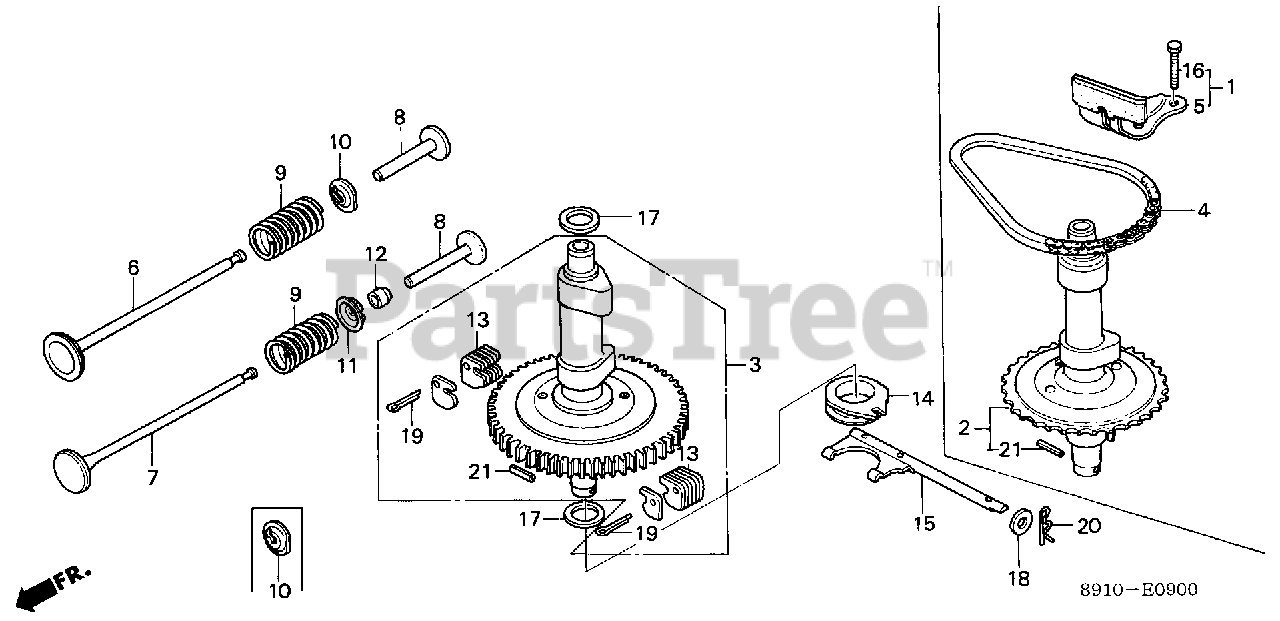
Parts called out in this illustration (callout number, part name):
3	CAMSHAFT ASSY.
6	VALVE, IN.
7	VALVE, EX.
8	LIFTER, VALVE (45.89MM)
8	LIFTER, VALVE (46.04MM)
8	LIFTER, VALVE (46.19MM)
8	LIFTER, VALVE (46.34MM)
9	SPRING, VALVE
10	RETAINER, VALVE SPRING
11	RETAINER, VALVE SPRING
12	ROTATOR, EX. VALVE
13	WEIGHT, GOVERNOR
14	SLIDER, GOVERNOR
15	SHAFT, GOVERNOR
17	WASHER, THRUST (18MM)
18	WASHER, PLAIN (6MM)
19	PIN, SPLIT (3.0X25)
19	PIN, SPLIT (3.0X45)
20	PIN, LOCK (6MM)
21	PIN, SPRING (2.5X16)
